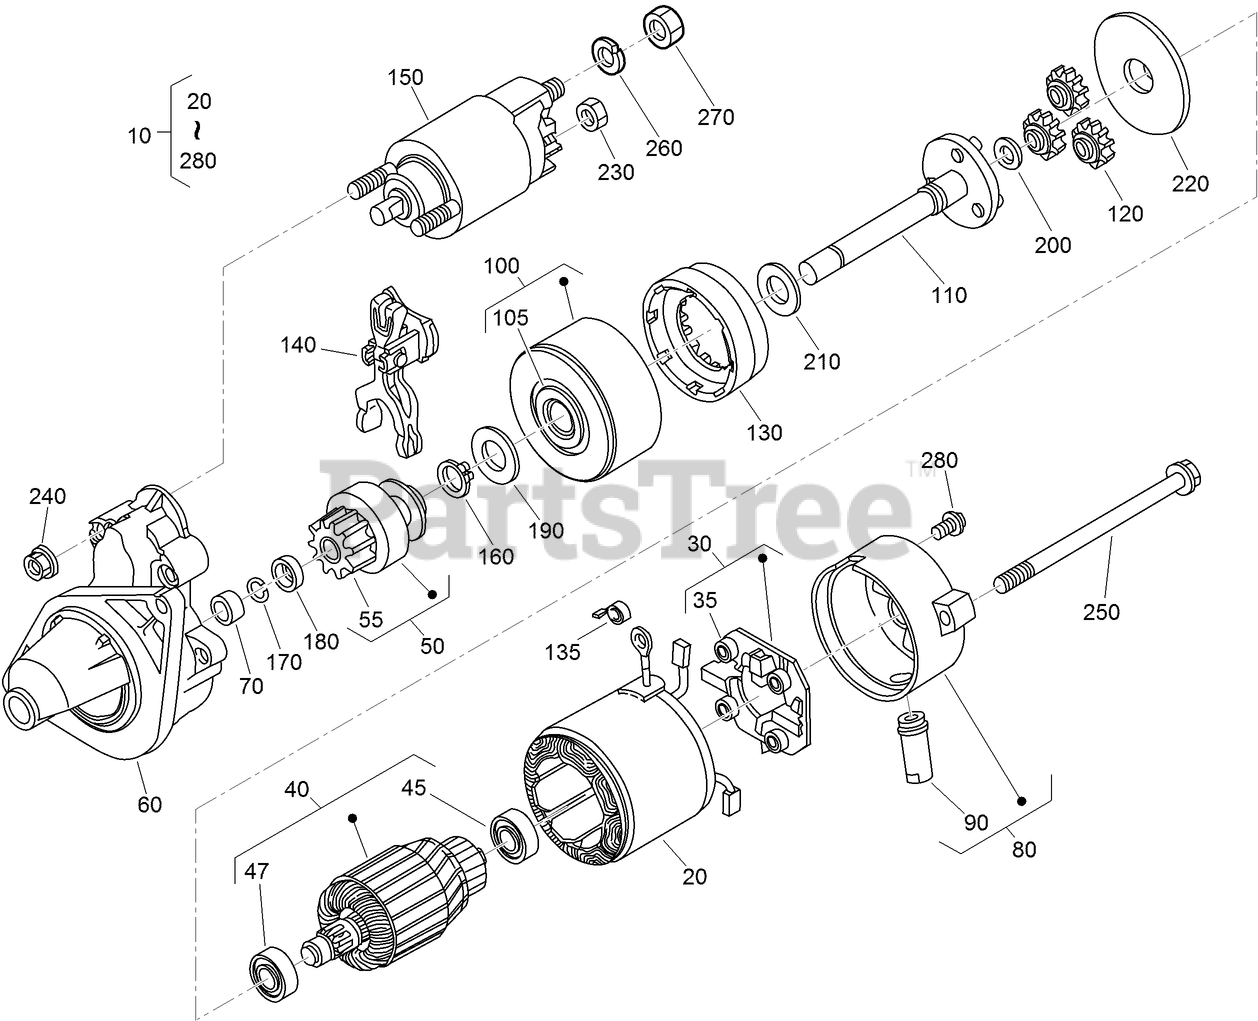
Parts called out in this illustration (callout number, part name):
10	STARTER ASM
20	STARTER YOKE ASM
30	HOLDER ASM
35	SPRING-BRUSH
40	ARMATURE ASM
45	BEARING-BALL
47	BEARING-BALL
50	STARTER CLUTCH ASM
55	GEAR-PINION
60	STARTER HOUSING ASM
70	BEARING
80	FRAME ASM
100	BEARING ASM
105	BEARING
110	STARTER SHAFT ASM
135	SPRING-BRUSH
150	MAGNETIC SWITCH ASM
160	RING-SNAP
170	RING-SNAP
180	COLLAR
190	WASHER-PLAIN
200	WASHER-PLAIN
210	WASHER-PLAIN
230	NUT-HEX
250	BOLT-THROUGH
260	WASHER-SPRING
270	NUT-HEX
